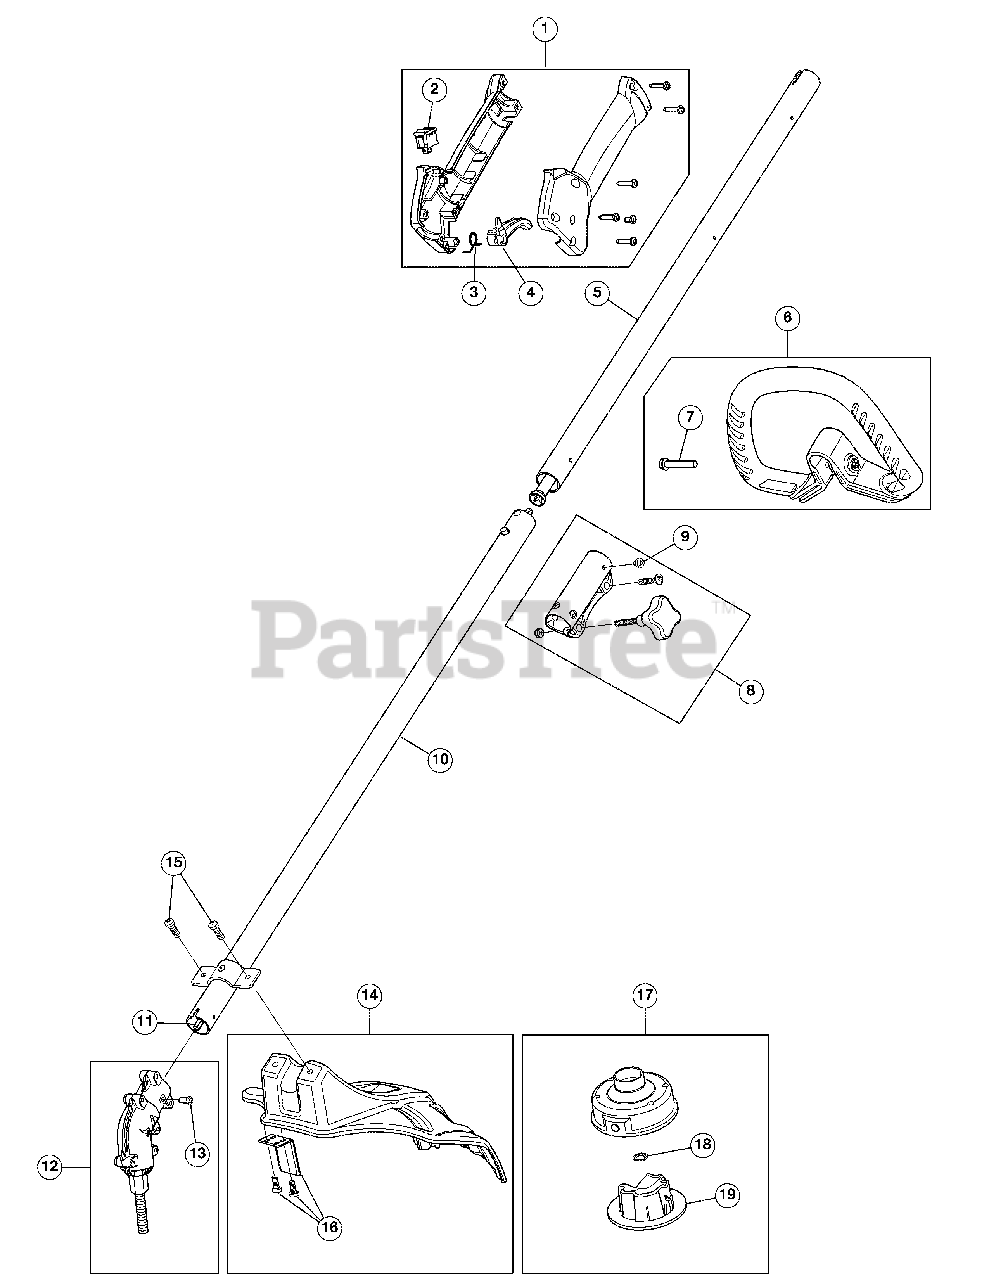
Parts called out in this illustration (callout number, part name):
1	Throttle Housing Assembly (Incl. 2 - 4)
2	Trigger Switch Assembly
3	Throttle Trigger Spring
4	Throttle Trigger
5	Upper Shaft Housing Assembly
6	D-Handle (Incl. 7)
7	D-Handle Hardware
8	Split Boom Coupler (Incl. 9)
9	Anti-Rotation Screw
10	Lower Shaft Housing Assembly (Incl. 11)
11	Lower Flexible Drive Shaft
12	Gear Box Assembly (Incl. 13, 17 - 19)
13	Anti-Rotation Screw
14	Shield Assembly (Incl. 15 & 16)
15	Shield Mounting Screws
16	Blade Assembly
17	Fixed String Head Assembly (Incl. 18 & 19)
18	Retainer
19	Fixed String Cap
